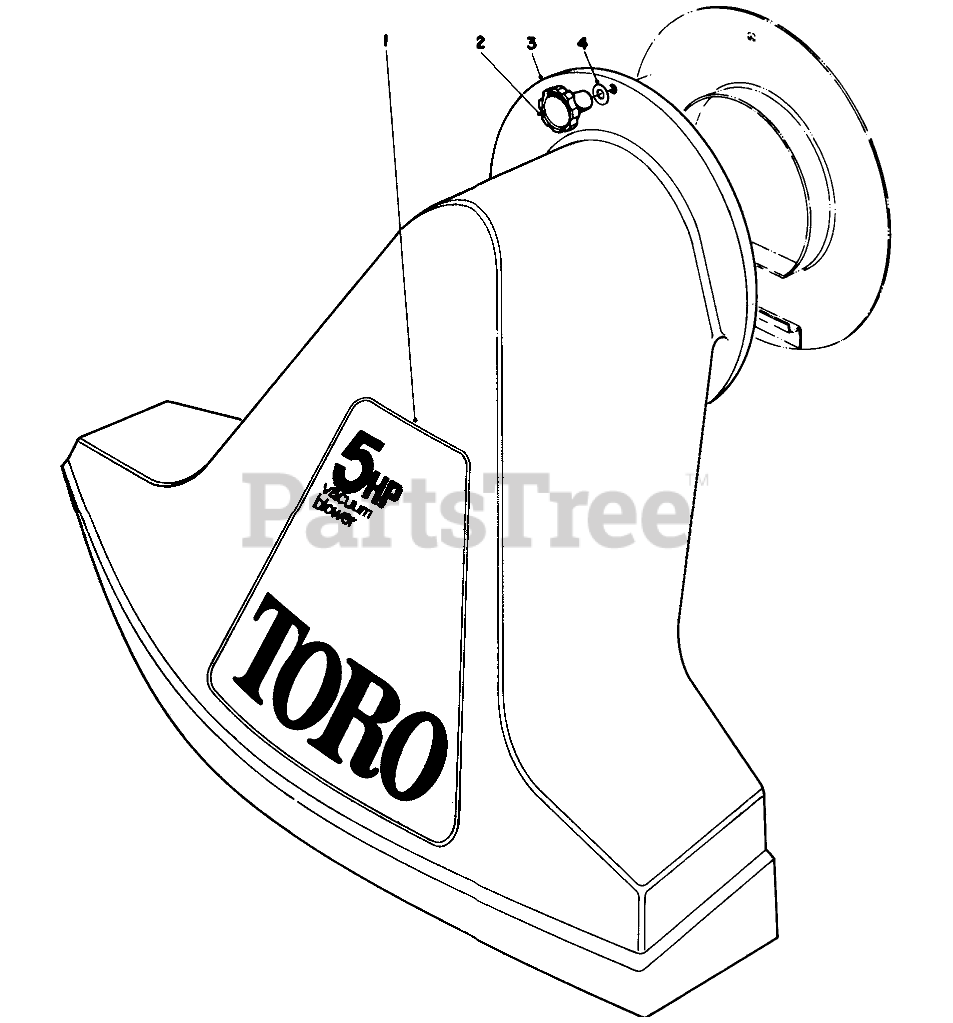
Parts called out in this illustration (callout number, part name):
1	Decal-Toro Model No. 62912
3	Snout
4	Washer
